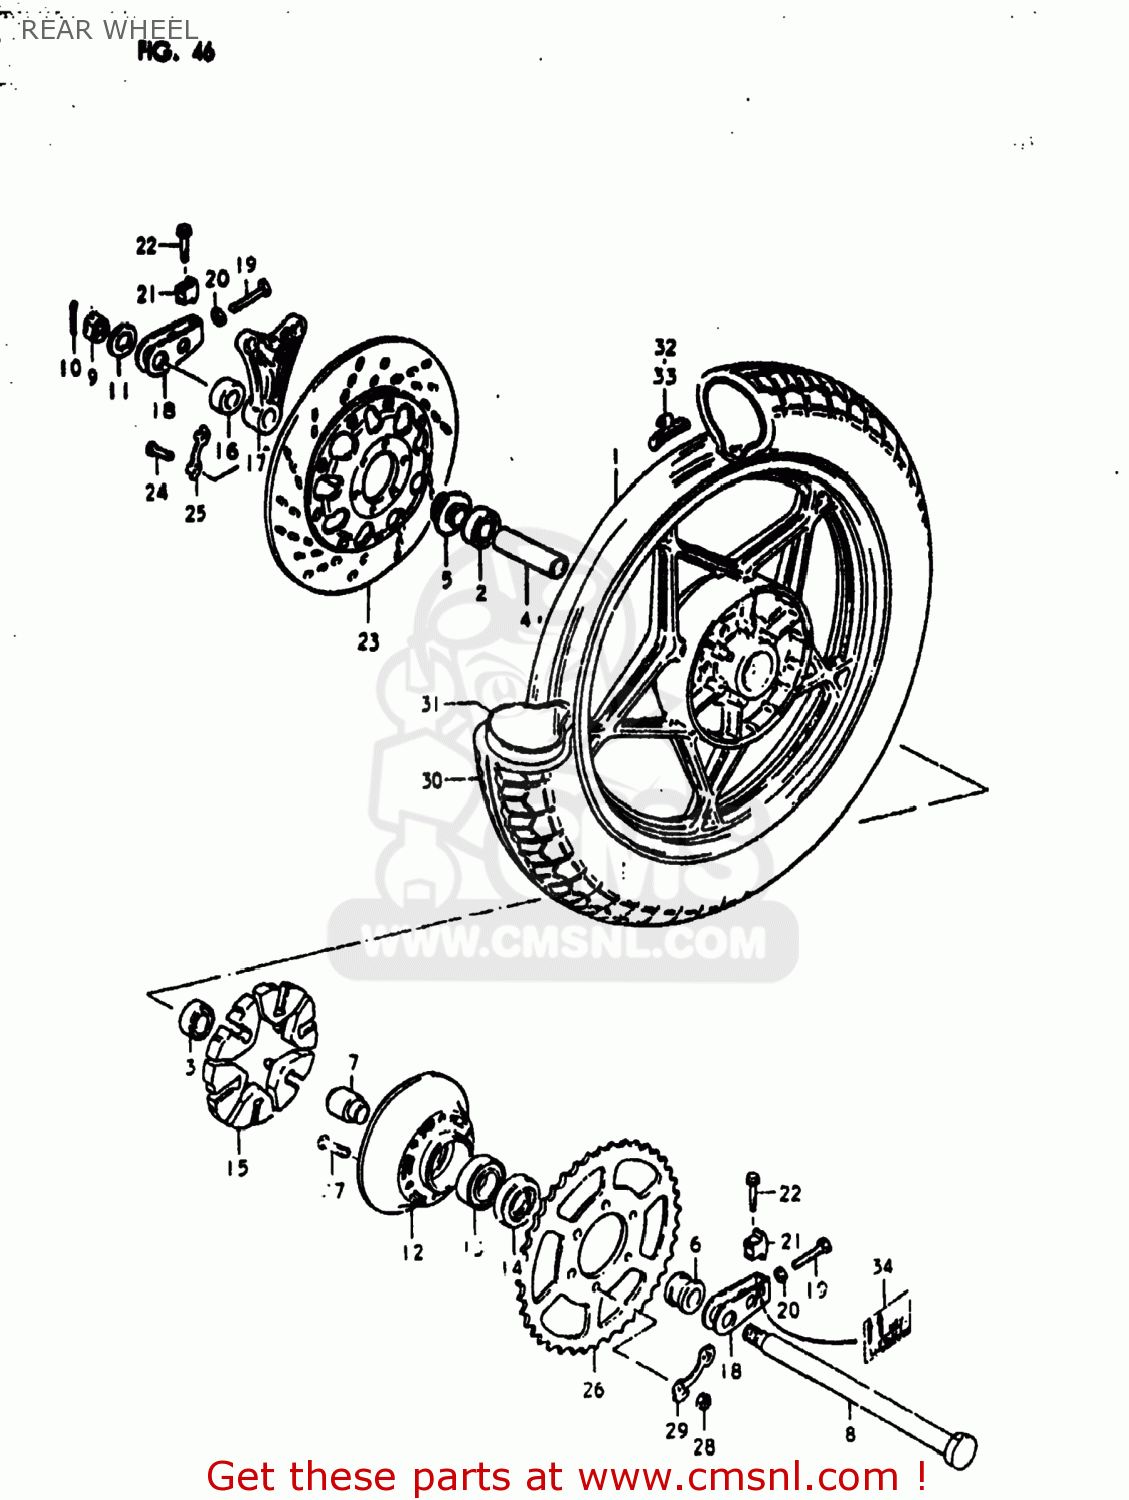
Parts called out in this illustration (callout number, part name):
1	WHEEL,REAR
2	BEARING WHEEL REAR(20X47X14)
3	BEARING, LH
4	SPACER(20.5X28X88)
5	SPACER,REAR AXLE
6	SPACER(20X33X28.3)
7	SPACER,REAR HUB BEARING
8	AXLE,REAR
9	NUT 18MM
10	PIN,COTTER
11	WASHER(19X34X4)
12	DRUM,REAR SPROCKET MOUNT
13	BEARING
14	SEAL,OIL(33X62X7)
15	ABSORBER,REAR HUB SHOCK
16	SPACER(20X38X12)
17	BRACKET,RR,CALIPER
18	ADJUSTER,CHAIN
19	BOLT
20	NUT
21	SUPPORTER,CHAIN ADJUST
22	BOLT (8X40)
23	DISC,RR BRAKE
24	BOLT(8X30)
25	WASHER
26	SPROCKET,REAR
27	BOLT
28	NUT
29	WASHER
30	TIRE
31	TUBE ASSEMBLY,WHEEL,INNER
32	BALANCER,WHEEL
33	BALANCER,WHEEL
34	LABEL,CHAIN WEAR INDICATOR
